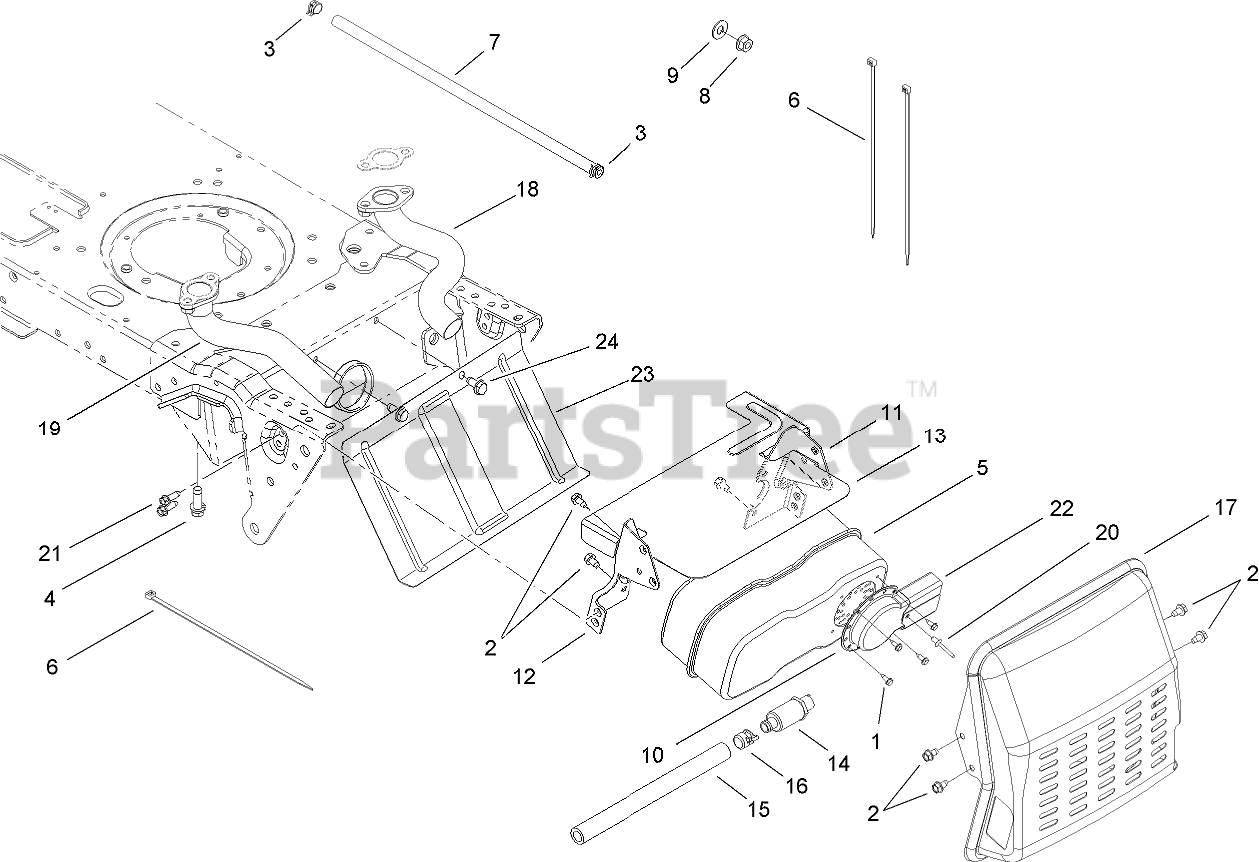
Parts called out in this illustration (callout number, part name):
1	SCREW-HWHTF
2	SCREW-HWHTF
3	CLAMP-HOSE
4	SCREW-TAP
5	MUFFLER-INLET, DUAL
6	TIE-CABLE
7	HOSE-FUEL
8	NUT-LOCK, FLANGE
9	WASHER-FLAT
10	DEFLECTOR-MUFFLER
11	BRACKET-MUFFLER, LH
12	BRACKET-MUFFLER, RH
13	SHIELD-HEAT
14	DRAIN-OIL
15	HOSE-DRAIN
16	CAP-DRAIN, OIL
17	MUFFLER HEAT SHIELD ASM
18	PIPE-EXHAUST, LH
19	PIPE-EXHAUST, RH
20	RIVET-POP
21	SCREW-TAP
22	DEFLECTOR-MUFFLER, LONG
23	SHIELD-HEAT, TRACTOR
24	SCREW-HWH
